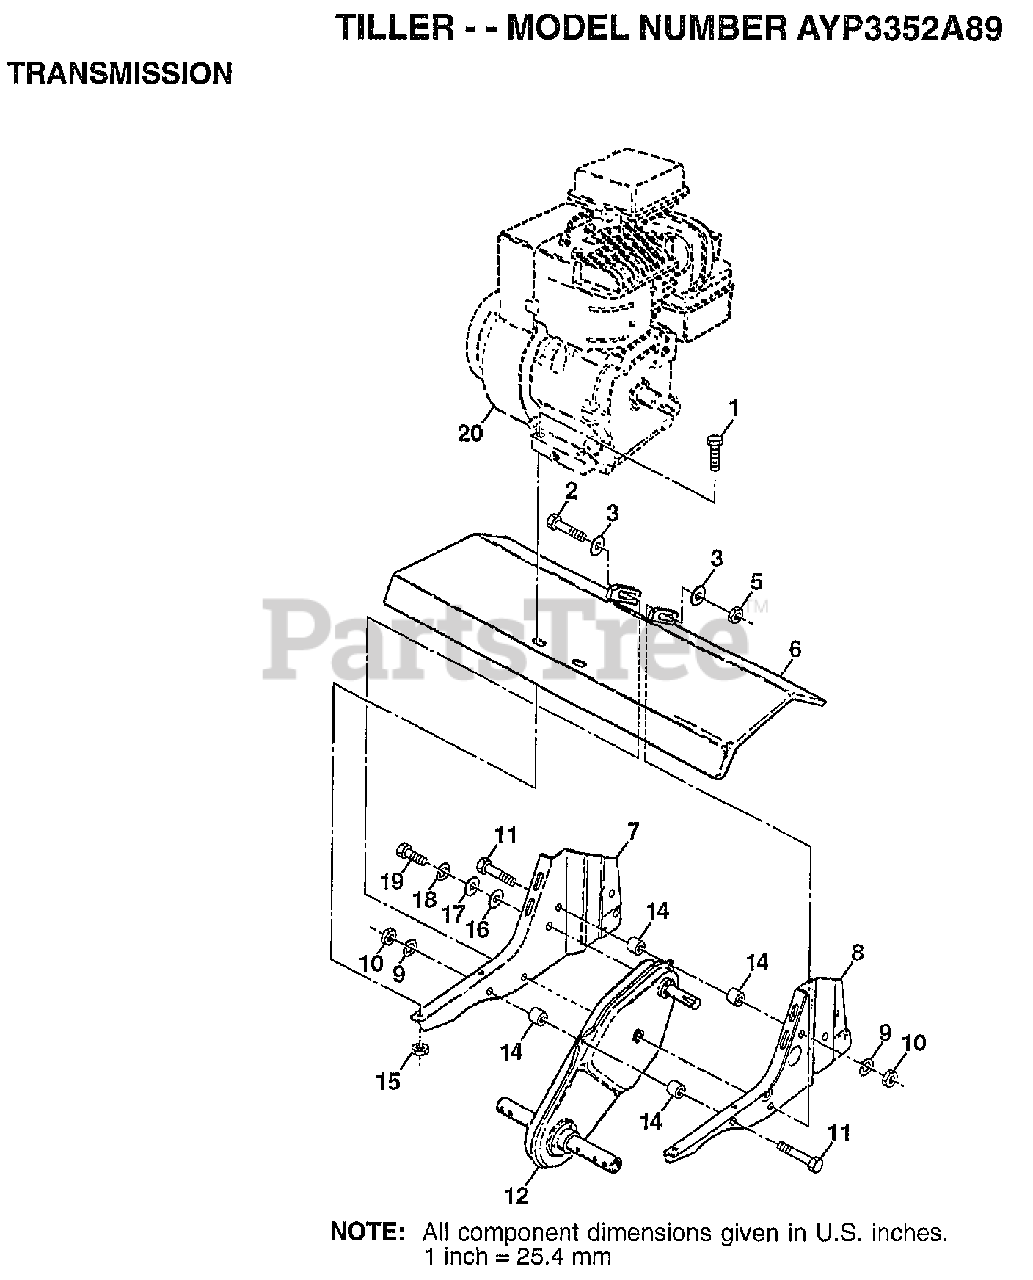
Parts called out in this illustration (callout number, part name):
1	BOLT.HEX.5/16-1.5
2	BOLT HEX 3/8-16
3	WASHER
5	NUT
6	"SHIELD, TINE"
7	BRACKET, ENGINE, R.H.
8	BRKT.ENGINE.LH
9	LOCKWASHER
10	NUT.HEX.5/16-18
14	SPLIT SPACER RT
16	WASHER
17	WASHER
18	LOCKWASHER
19	BOLT
